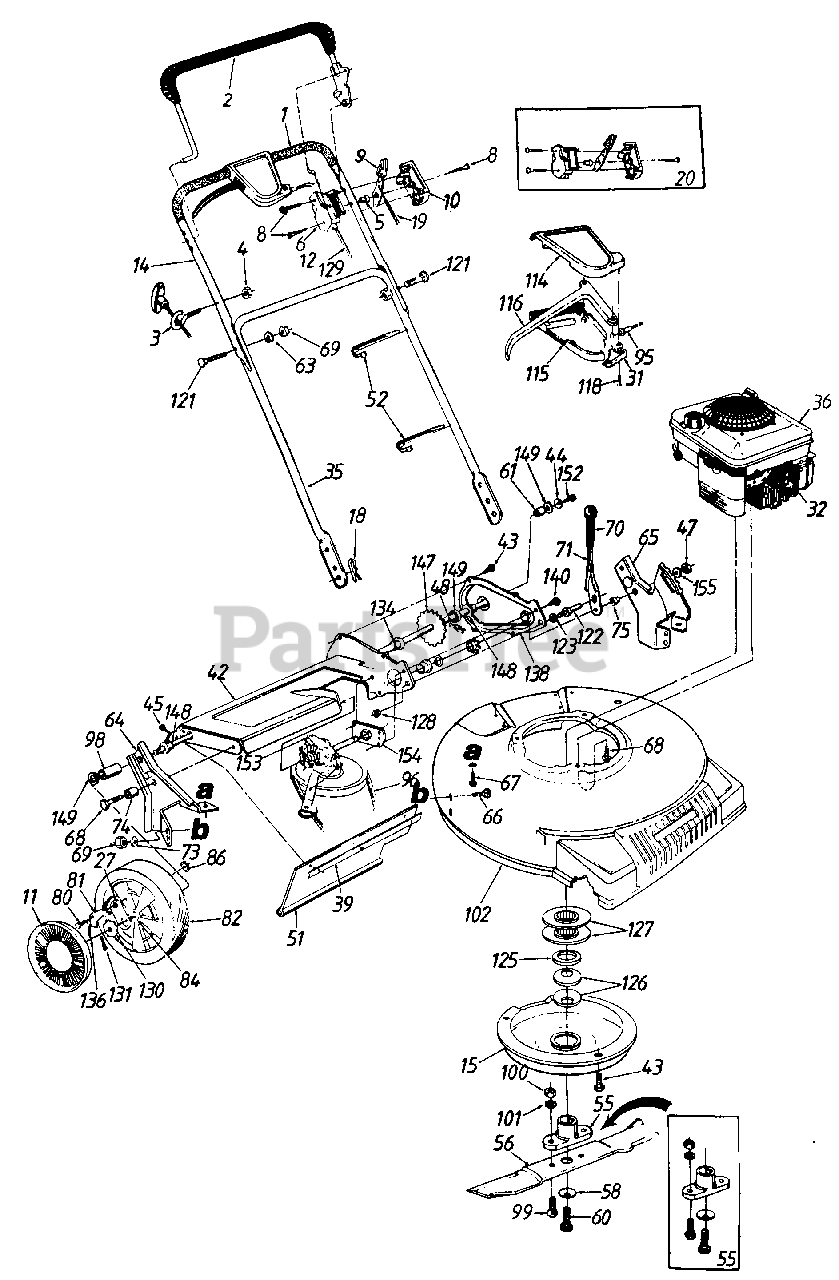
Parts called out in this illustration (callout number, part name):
1	GRIP-FOAM
3	ROPE-GUIDE EYEBOLT
4	NUT-INS LOCK 1/4-20
5	PIN-CONTROL DISC
6	PANEL HALF-CLUTCH
8	SCREW-TRUSS MACH
9	LEVER-THROTTLE CONT-REV
10	PANEL HALF-CONTROL
11	HUB CAP
14	HANDLE-UPPER
15	COVER-BELT
18	PIN-INTERN COT-5/16 DIA
19	WIRE-THROTTLE-52 IN
20	KIT-THROTTLE CONTROL
27	PLATE-PAWL
31	COVER-SP CONTROL
32	INSULATOR-SPARK PLUG
35	LOWER HANDLE
39	STRIP-RETAINING
42	AXLE ASSY-CHAIN
43	SCREW-HEX B-TAP 1/4 X .38
44	WASHER-SPRING BELL
45	SCREW-HEX WASH HD
47	NUT-HEX LOCK 3/8-24
48	#48 CHAIN-1/2 PITCH-38 LINKS
52	TIE-CABLE
55	KIT-BLADE ADAPTER SPLINED
56	BLADE-21IN-MULCHING
58	WASHER-BELL
60	SCREW-HEX 7/16-20 X 2.50
61	SPACER-.513 ID X .703 OD X .69
63	WASHER-LOCK-5/16
64	BRACKET ASSY-HDLE-RH
65	BRACKET ASSY-HDLE-LH
66	BOLT-CARRIAGE 5/16-18 X .62
67	SCREW-HEX WASH HD 5/16-18X1/2
69	NUT-HEX 5/16-18
71	LEVER-SPRING
73	WASHER-BELL .337 X .867 X .057
74	SPACER
75	SPACER-SHLD .500 X .100
80	SCREW-SHLD .342 DIA X .268
81	PAWL
82	WHEEL ASSY W/TIRE
86	NUT-FLAT WELD 1/4 X 20
95	CABLE-CLUTCH CONTROL
96	BELT-V 3/8 X 31.0
99	SCREW-HEX 3/8-24 X 1 LG
100	NUT-HEX 3/8-24
101	WASHER-LOCK-3/8
115	COVER-HALF CONT-LWR
116	LEVER-CONTROL
118	SCREW-FL C-SUNK AB
121	BOLT-CARRIAGE-CURV 5/16-18 X 1.38
122	PIN-SHLD 3/8-24X1.43 LG
123	WASHER-LOCK-3/8
125	SPACER-CRANKSHAFT 1.005X1.625X.296
126	WASHER-BELL 1.008X 1.625 X .042
127	PULLEY HALF-SERRATED
128	NUT-HEX JAM 3/8X24
129	WIRE-THROTTLE
130	RATCHET
131	PIN-COTTER-1/8 DIA X 1.00
134	BEARING-HEX FLANGE
136	SPRING-NYLON
147	SHAFT ASSY-AXLE-RR
148	BEARING-HEX FLANGE .506 ID
149	WASHER-FL-.531 X .930 OD X .050
152	SCREW-1/4-20 X .62
153	TRANSMISSION-COMP
155	WASHER-FL-.385 ID X .87 OD X .06
